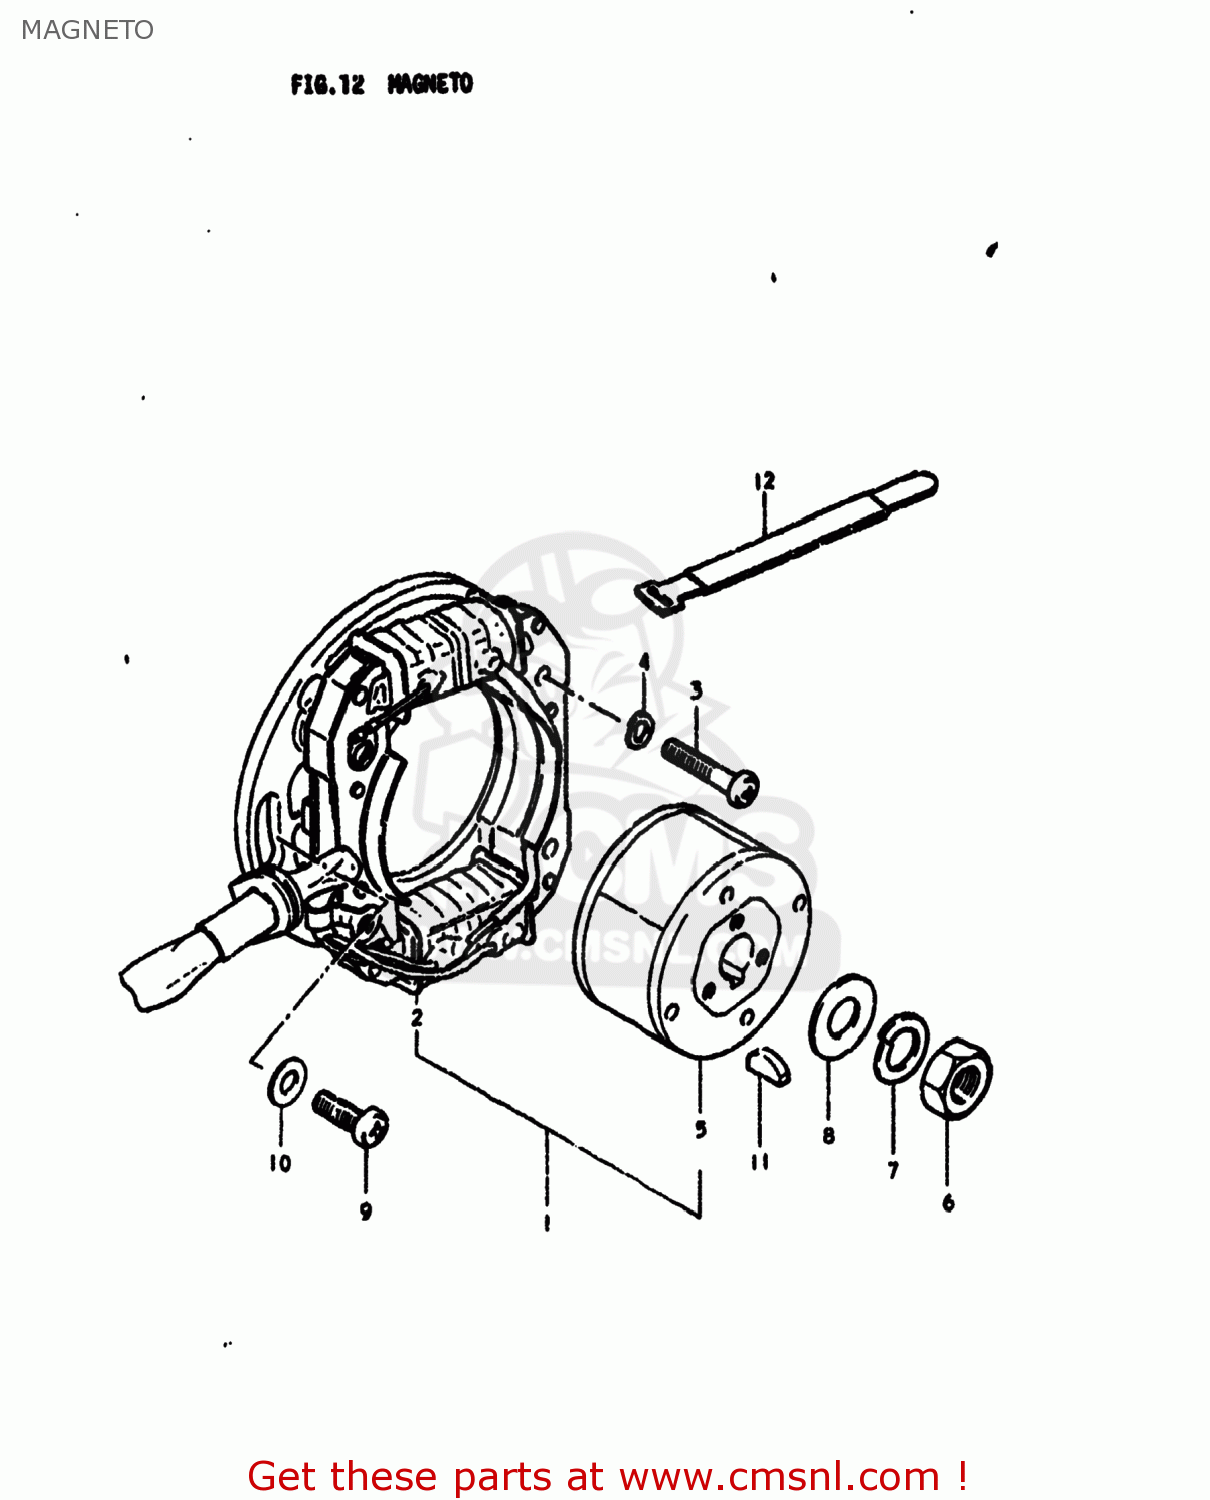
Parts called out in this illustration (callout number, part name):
1	MAGNETO ASSEMBLY
2	STATOR ASSEMBLY
3	SCREW 5X20
4	LOCK WASHER
5	ROTOR ASSEMBLY
6	NUT (10MM)
7	LOCK WASHER
8	WASHER
9	SCREW
10	WASHER
11	KEY 4MM
12	CLAMP
